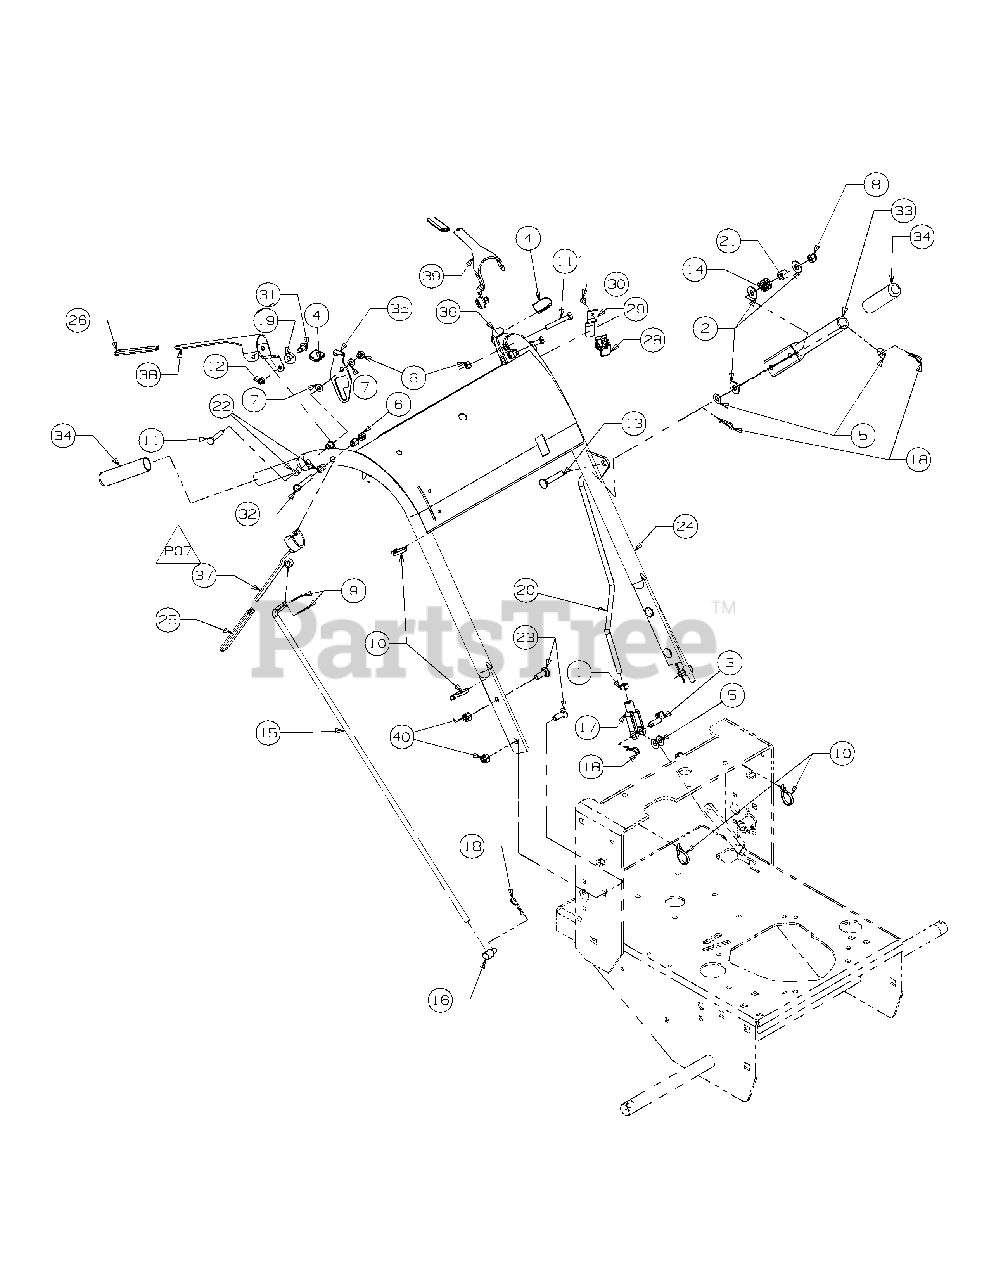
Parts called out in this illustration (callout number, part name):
1	Hex Nut, 3/8-16
2	Flat Washer, 3/8 Zinc
3	Clevis Pin, 3/8 x 1-1/8 Zinc
4	Grip, Neutral Latch, 1.25"
5	Flat Washer, 3/8 Zinc
6	Nylock Nut, 5/16-18
7	Flat Washer, 5/16 Zinc
8	Lock Nut, Nylon Insert, 3/8-16
9	Cotter Pin, 3/32 x 3/4, Zinc
10	Cable Tie, 3/16 x .05 x 7.4
11	Hex Cap Screw, 5/16-18 x 2
12	Lock Nut, Nylon Insert
13	Carriage Bolt, 3/8-16 x 2
14	Spring, .850 OD x 1
15	Steering Control Rod
16	Joint Swivel
17	Yoke, 3/8-16 Female
18	Hair Pin 3/8-1/2
19	Control Rod, Hydro Spacer
20	Blade Clutch Rod
21	Spring Sleeve
22	Nylon Bushing
23	Carriage Bolt, 3/8-16 x 1-1/4
26	Operator Control Sleeve, Yellow
28	Switch Mounting Snap
29	Operator Presence Return Spring
30	Hex Index Washer Screw, 0.500
31	Shoulder Screw, .38 x .412, 1/4-28
32	Hex Cap Screw, 5/16-18, 2.00
35	Neutral Latch, Right Hand
36	Neutral Latch, Left Hand
